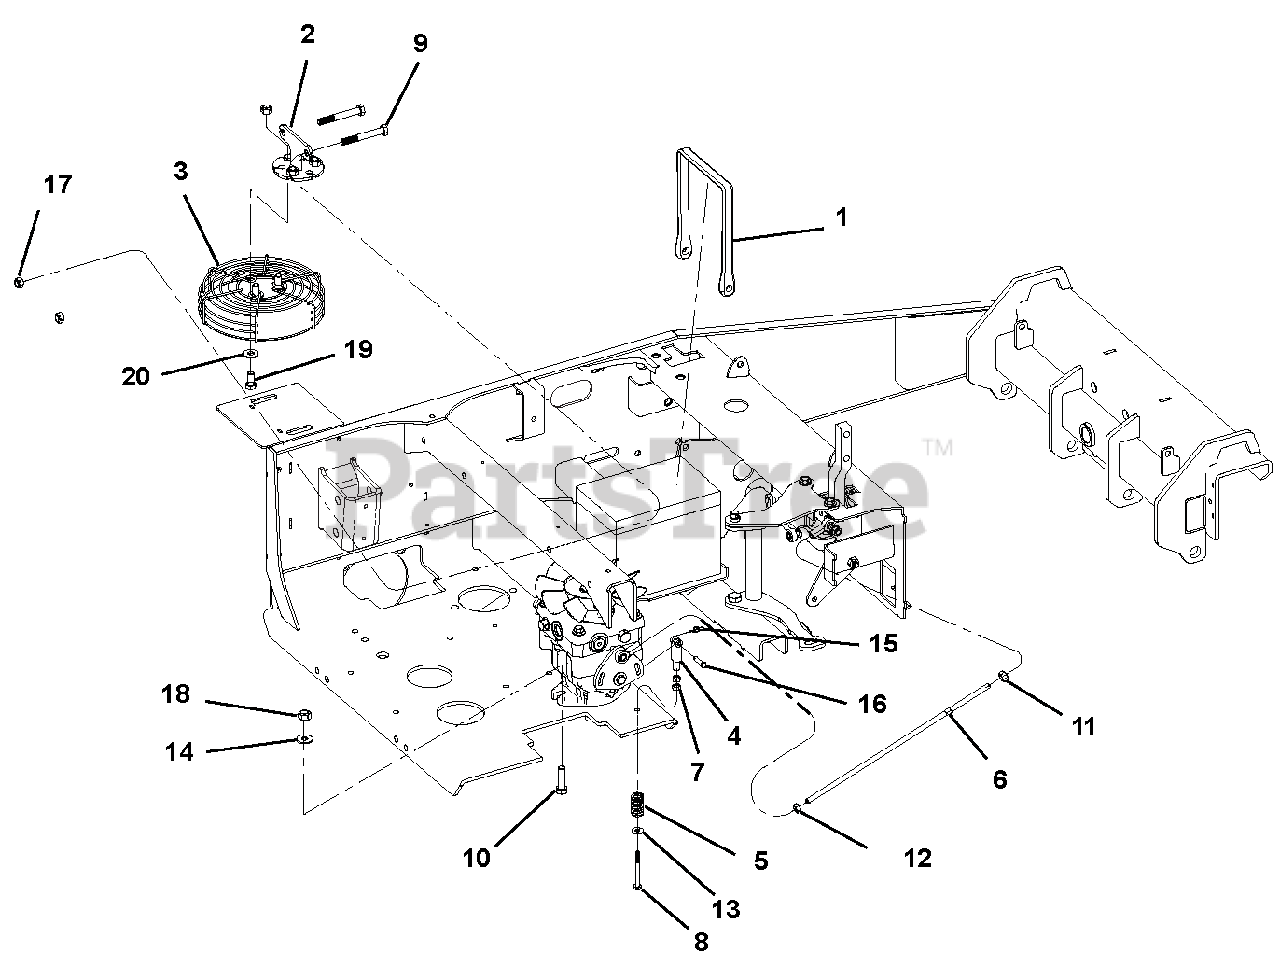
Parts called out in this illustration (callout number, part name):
1	BAND 15"
2	WLDT, FAN SHIELD MOUNTING
3	GRILL, 7" FAN
4	YOKE, 1/4-20 RH ADJUSTABLE
5	SPRING, COM .784X.092X1.50
6	ROD, PUMP CONTROL
7	@NUT-LK-NYL .250-20 YWZC
8	BOLT, 1/4-20X2.75 SOC 8 Y
9	@BLT-HEX .38-16X2.75 GR5 YWZC
10	@BLT-HEX .44-14X1.50 GR5 YWZC
11	NUT-HEX .312-24 YWZC
12	NUT-HEX .312-24 LH GR5 YWZC
13	@WSHR-FL-STL.312X.734X.065 YWZ
14	@WSHR-FL-STL.438X1.00X.083 YWZ
15	RING, RUE .250 X .041 X .844
16	PIN, CVS .250X1.00X.859 Y
17	NUT-LK-FLG .375-16 PL
18	NUT-LK-CROWN .437-14 PL
19	@BLT-HEX .38-16X.75 GR5 YWZC
20	@WSHR-FL-STL.38X.875X.083 YWZC
